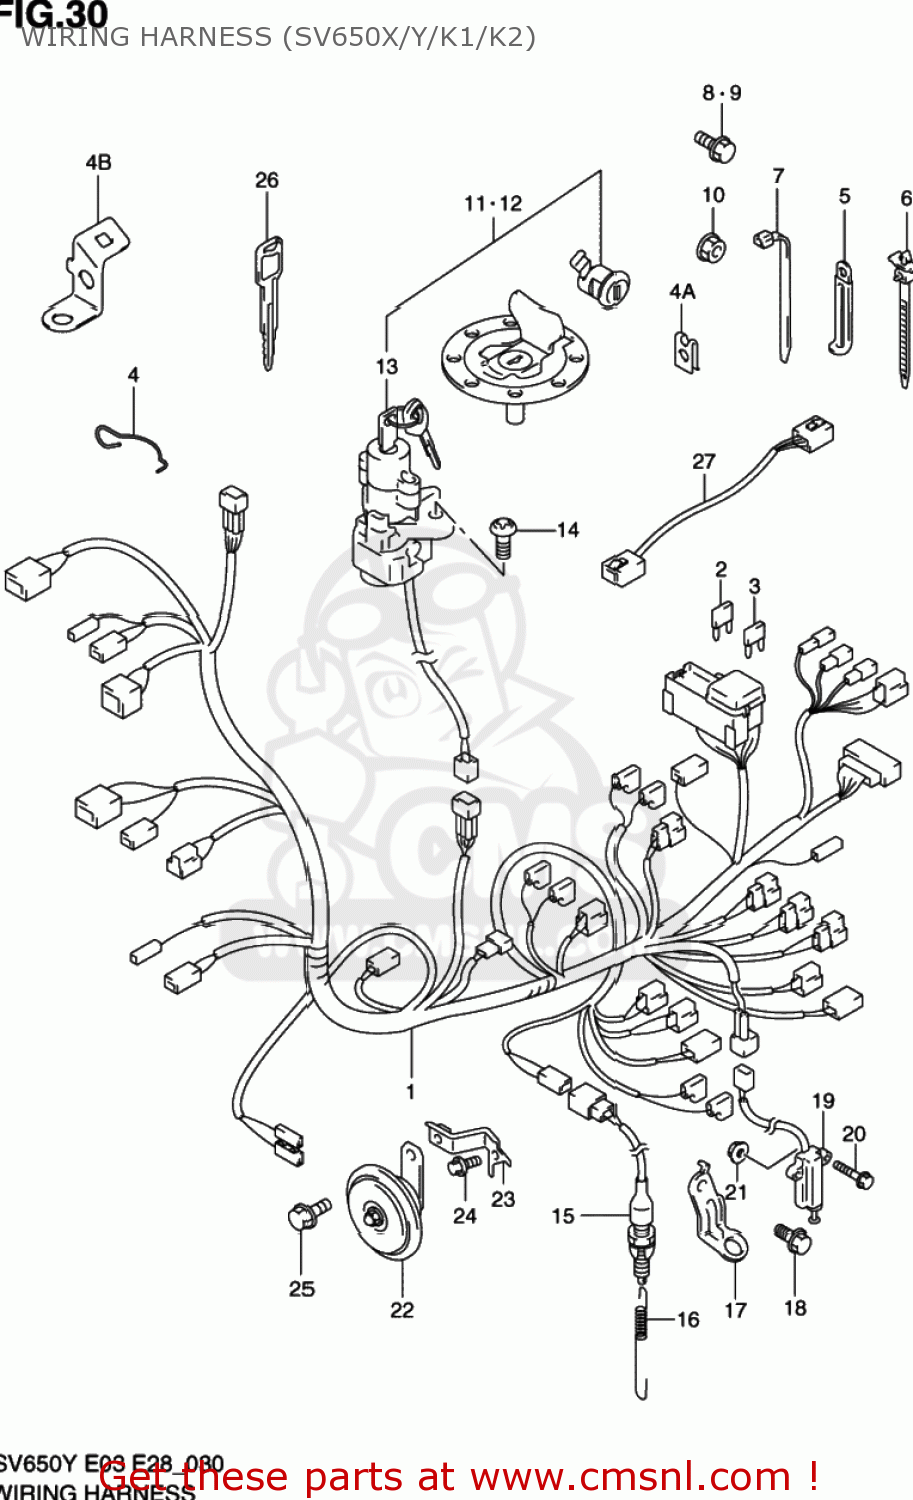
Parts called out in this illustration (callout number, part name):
1	HARNESS,WIRING
2	FUSE(10A)
3	FUSE(15A)
4	GUIDE,WIRING HARNESS
4A	NUT,FR FENDER
4B	HOLDER,COUPLER
5	CLAMP(L:65)
6	CLAMP
7	CLAMP(L:125)
8	BOLT
9	BOLT
10	NUT
11	LOCK SET
12	LOCK SET
13	LOCK ASSY,STEE
14	BOLT(8X20)
15	SWITCH ASSY,STOP LAMP
16	SPRING
17	BRACKET,STOP LAMP SWITCH
18	BOLT
19	SWITCH ASSY,SIDE STAND
20	BOLT(6X20)
21	NUT
22	HORN ASSY
23	BRACKET,HORN
24	BOLT
25	BOLT
26	KEY,BLANK
27	WIRE,STARTER CONTROL
